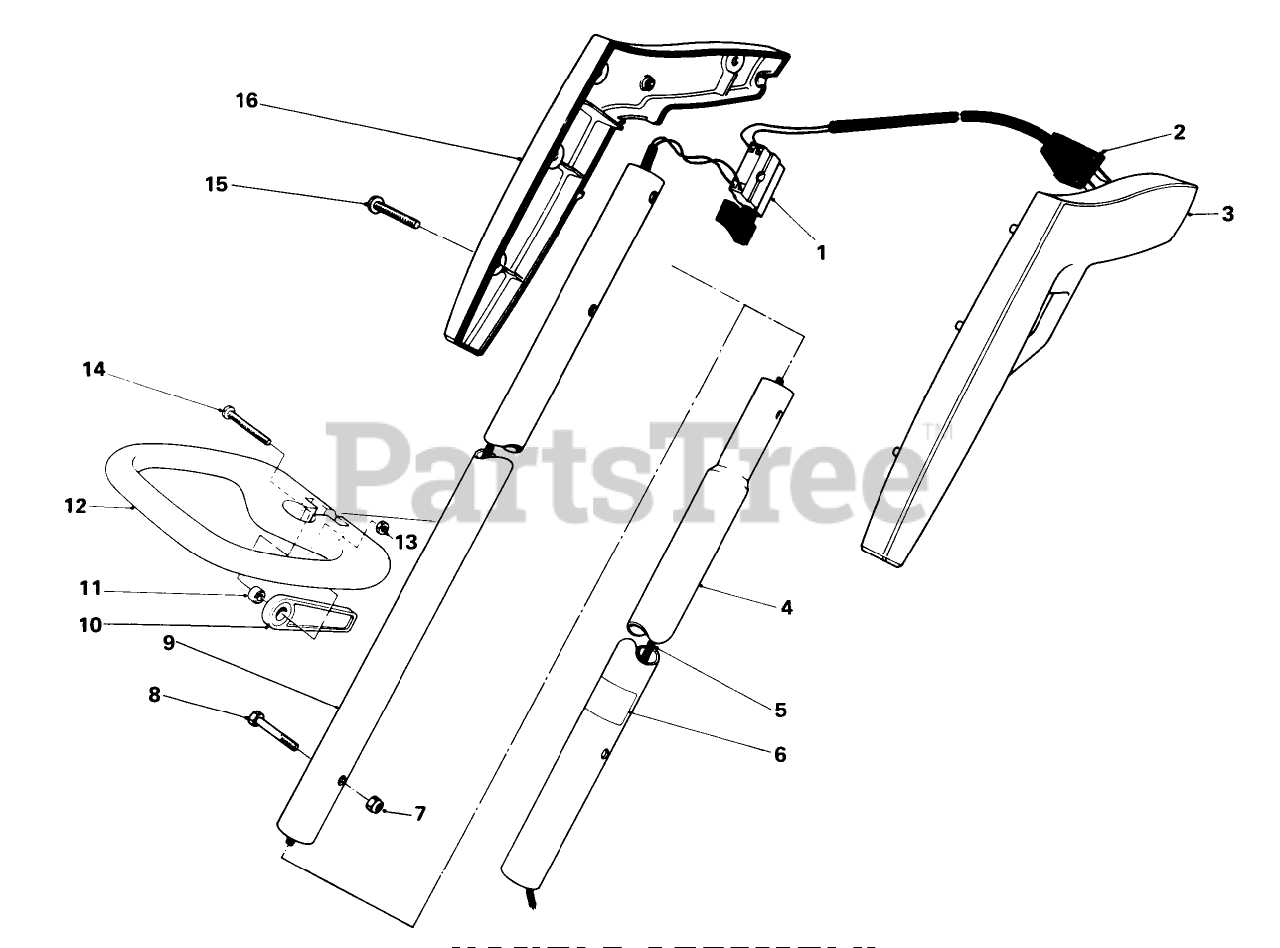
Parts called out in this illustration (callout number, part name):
1	SWITCH SINGLE SPEED
2	Power Cord
3	Grip L.H.
4	Tubing-Lower Extension
5	Wire Harness
6	Decal-Serial
7	NUT-LOCK, NI
8	HEX HD MACHINE SCREW
9	Tubing-Upper Extension
10	Cam Lock
11	Spacer
12	Support Handle
13	NUT-HEX
14	Screw
15	Screw
16	R.H. GRIP
